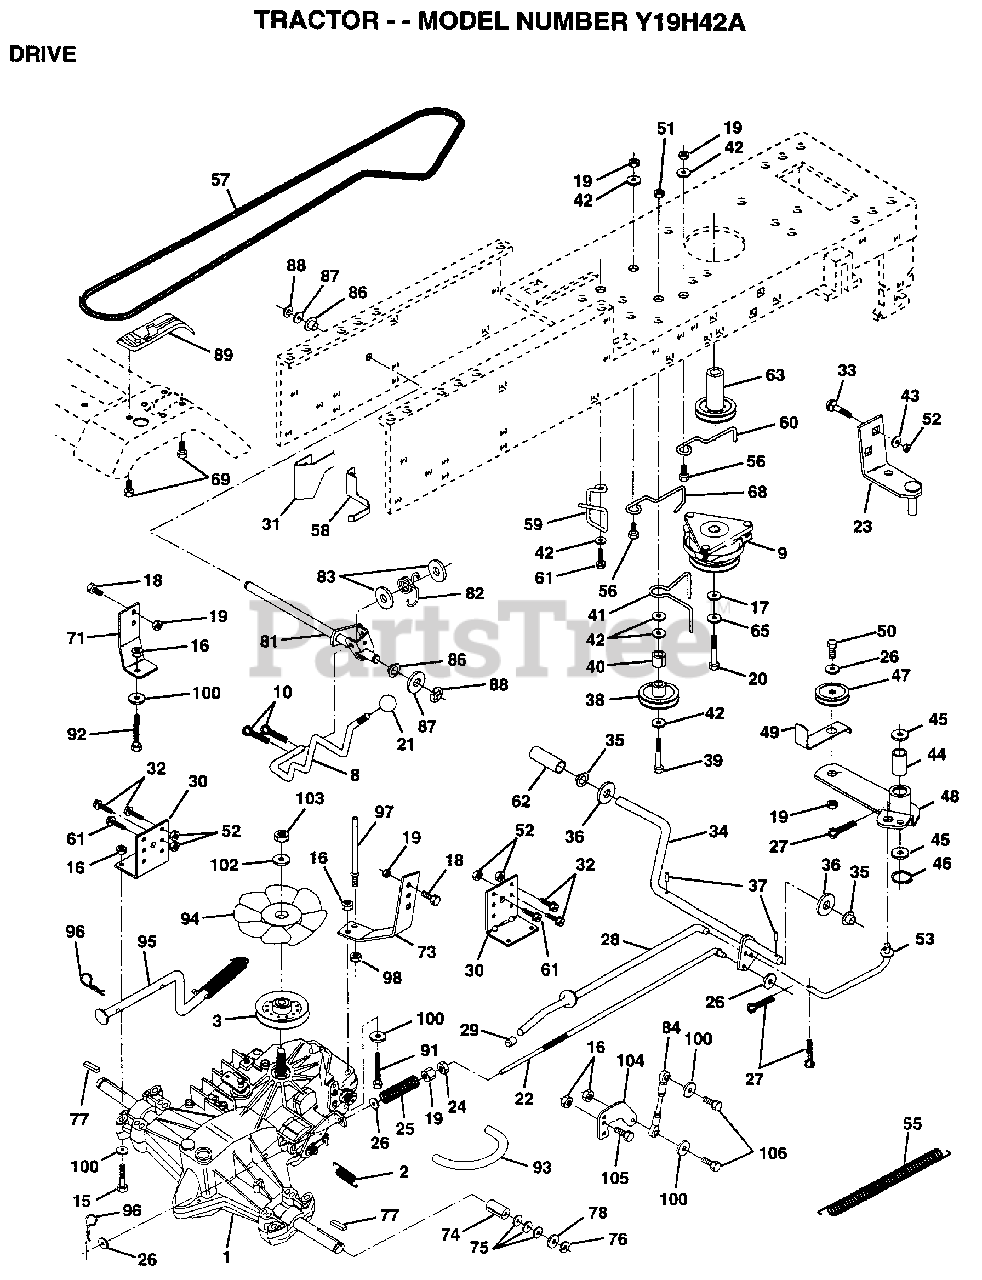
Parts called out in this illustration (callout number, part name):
2	SPRING RET BRAKE
3	PULLEY.TRANSAXLE
8	ROD SHIFT FEND YT
10	PIN COTTER 1/8
15	BOLT HEX
16	NUT
17	WASHER
18	BOLT
19	NUT
21	KNOB.DUCKHEAD.1/2
22	ROD.BRAKE.HYDRO.
23	BRACKET.ASM.MTG
25	SPRING ROD LT
26	WASHER
27	COTTER PIN
28	ROD.BRAKE.PARK.LT
29	PLUNGER CAP T
30	TRANSAXLE MTG BKT
31	KEEPER,BELT LH T
32	BOLT
33	BOLT
34	SHAFT.PEDAL.FOOT
35	NYLON BEARING
36	WASHER LT
38	PULLEY.IDLER.FLAT
39	BOLT
40	SPACER T
41	BELT KEEPER LT
42	WASHER
43	WASHER T
44	LY, BEARING
45	WASHER LT
46	KLIP RING
49	RETAIN BELT
55	SPRING, RETURN LT
57	"BELT.GD DRV 82"""
58	KEEPER BELT LH
59	KEEPER BELT CNTSP
61	SCREW
62	PEDAL COVER T
63	PULLEY CLU ELEC
65	LOCKWASHER
68	KEEPER,BLT ENG LT
69	SCREW HEXWSH H-L
71	STRAP TORQ LH HYD
73	STRAP TORQ RH HYD
75	WASHER (2513009)
76	E-RING LT
77	SQUARE KEY
78	WASHER
82	SPRING,TORSION
83	WASHER
84	ROD.TIE.BALL.4.75
86	BUSHING
87	WASHER D
88	KLIP RING
92	HEX BOLT
93	"LINE FUEL HYD 4"""
94	"FAN 7"" HYDRO"
96	RETAINER M (5 2)(3 2)
97	BOLT KEEPER RH
98	NUT
100	WASHER M
102	WASHER BELLEVILLE
104	ARM CONTROL HYDRO
105	SCREW CAP 5/16-18
106	BOLT
